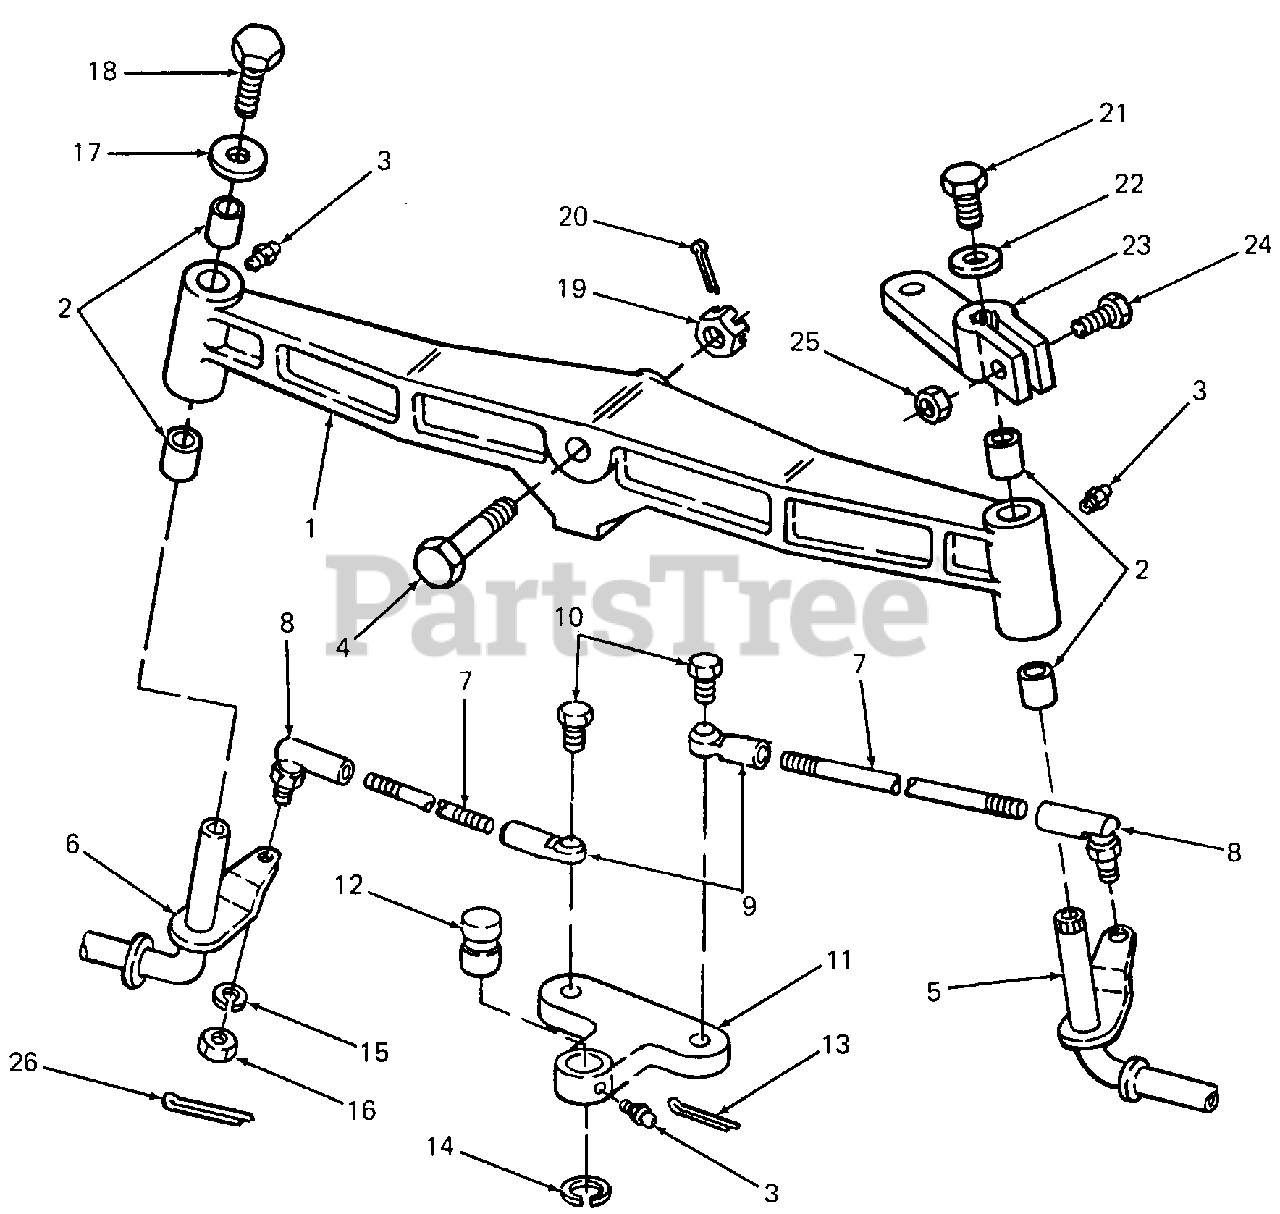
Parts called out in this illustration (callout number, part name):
1	Axle Assy, Front
3	Fitting, Lube, 3/16 Drive
4	Bolt, Hex, 3/4-10 X 5.0 Lg GR5 w/Hole
8	Ball Joint, 1/2-20
9	Alignabal End
10	Screw, Hex Cap, 3/8-16 X 1.5 Lg GR5 w/Hole
11	Steering Lever w/Fitting
12	Pin, Steering Pivot
13	Pin, Cotter, 3/32 Dia X 1.0 Lg
14	Ring, Retaining
15	Washer, Lock, 1/2 Dia
16	Nut, Hex Castle, 1/2-20 GR5
17	Washer, Flat, .531 X 1.75 X .090 Thk
18	Screw, Hex Cap, 1/2-13 X .75 Lg GR5
19	Nut, Hex Castle, 3/4-10
20	Pin, Cotter, 1/8 X 1.5 Lg
21	Screw, Hex Cap, 3/8-24 X 1.00 Lg GR5
22	Washer, Flat, .406 X 1.5 X .112 Thk
23	Arm, Steering
24	Screw, Hex Cap, 5/16-18 X 1.38 Lg GR5
25	Nut, Hex Center Lock, 5/16-18 GR5
26	Pin, Cotter, 3/32 Dia X 1.25 Lg
